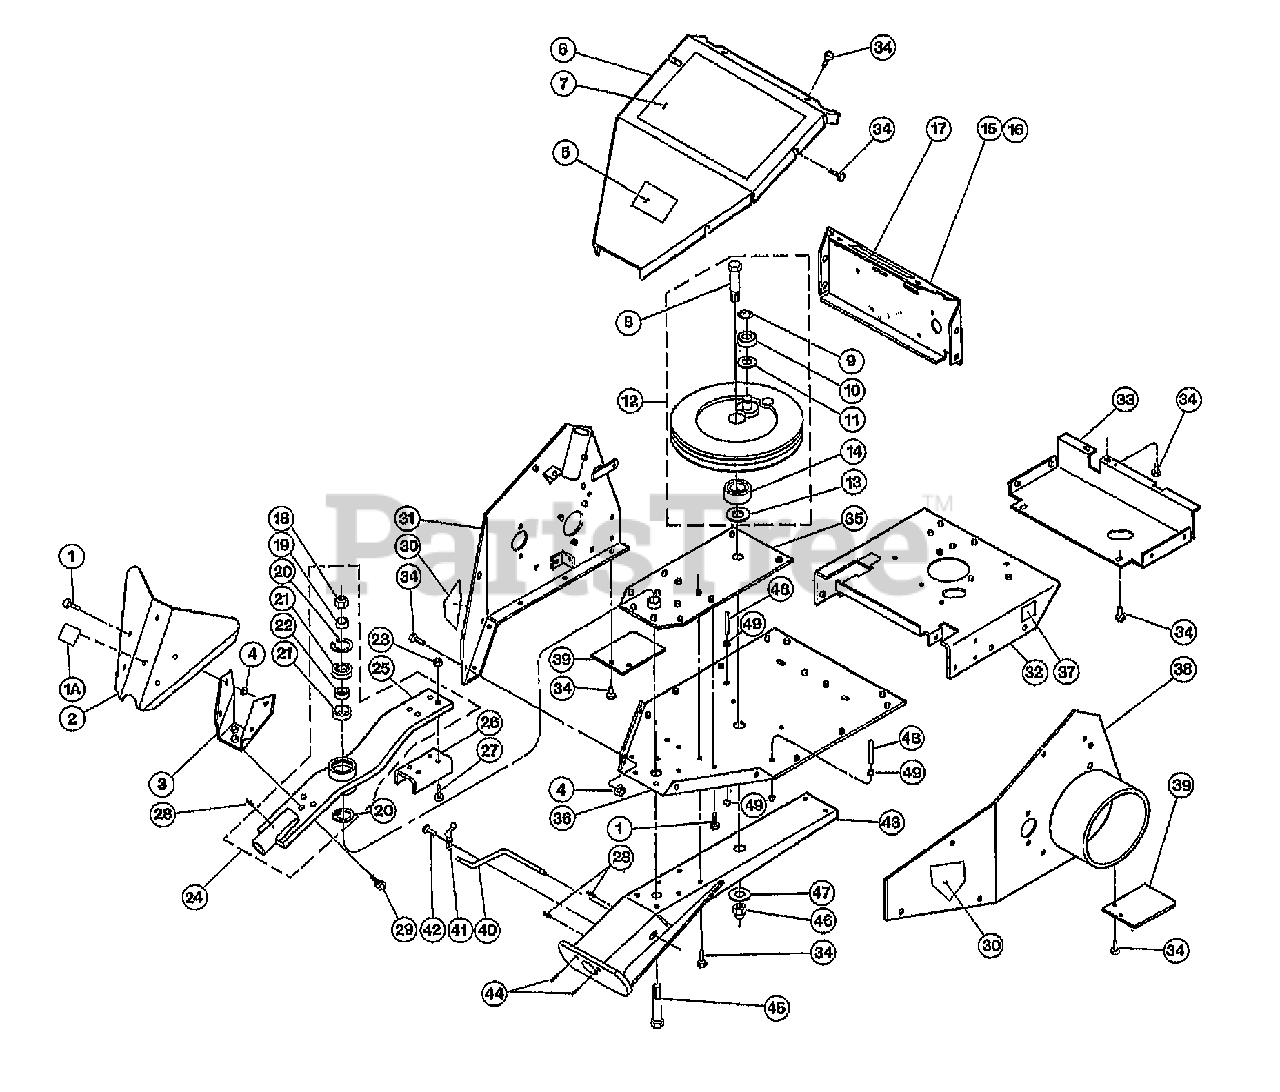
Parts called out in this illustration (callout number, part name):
1	SCR-HFLK 5/16-18X.62 G5ZP
1A	DECAL-DANGER WEED DEFLET
2	DEFLT-WEED W/DECALS #40169 (INDEX #48)
3	DEFLECTOR-WEED PNT
4	NUT-HFLK 5/16-18 ZP
5	DECAL-DANGER (CUTTER BAR)
6	HOOD-PNT W/DECALS #40160 (INDEX #5)
7	DECAL-LOGO TRAILBLAZER
8	BOLT-FLYWHEEL (SPECIAL)
9	RING-RETAIN EXT .669 ID
10	BEARING-ECCENTRIC
11	SHIM-1.125X.671X.048
12	ASSM-FLYWHEEL
13	SHIM-1.375X.789X.048
15	HOOD, REAR STANDARD START MODELS ONLY
16	HOOD-REAR ELECTRIC START MODELS ONLY (INCL. DECALS - INDEX #17)
17	DECAL-SHRT CIR/CHRG INSTR
18	NUT-H/LK 5/8-11
19	WASHER-.5625
20	RING-RETAINING INT 1.575
21	BEARING-DRIVE ARM
22	SPACER-.6725X.96X.572
23	NUT-H/LK 5/16-18 NYLOCK
24	ASSM-DRIVE ARM, INCL. TWO RETAINING RINGS, BEARING, AND SPACERS
26	CHANNEL-DRIVEARM MACH
27	SCR-FH HXSKT 5/16-18X1.25
28	FITTING-GREASE STREIGHT
29	SCR-HFLK 5/16-18X1.00 ZP
30	DECAL-DANGER CUT FINGER
31	PLATE-RT FRAME, INCL. DECAL (INDEX #30)
32	ENGINE DECK
33	COVER-BELT CUTTERBAR RED
34	SCR-HFLK 5/16-18X.75 ZP
35	PLATE-#40146P
36	PLATE-FRAME BTM 40096P
37	DECAL-OIL DRAIN TUBE
38	PLATE-FRAME LT W/DECAL (INDEX #30)
39	PLATE-WEED GUARD
40	PIN-CRANK
41	SPRING CLAMP-CRANK PIN
42	SCR-HW M10-32X.5 THRD ROLL
43	HOLDER-CUTTERBAR 40118P
44	PIN-SPIROL .375X 1.0
45	BOLT-DRIVE ARM
46	NUT-H/LK 3/4-10
47	WASHER-2.0X.75X.15 ZP
48	PIN-BELT GUIDE
49	NUT-TOP/LK 5/16-18 ZP
